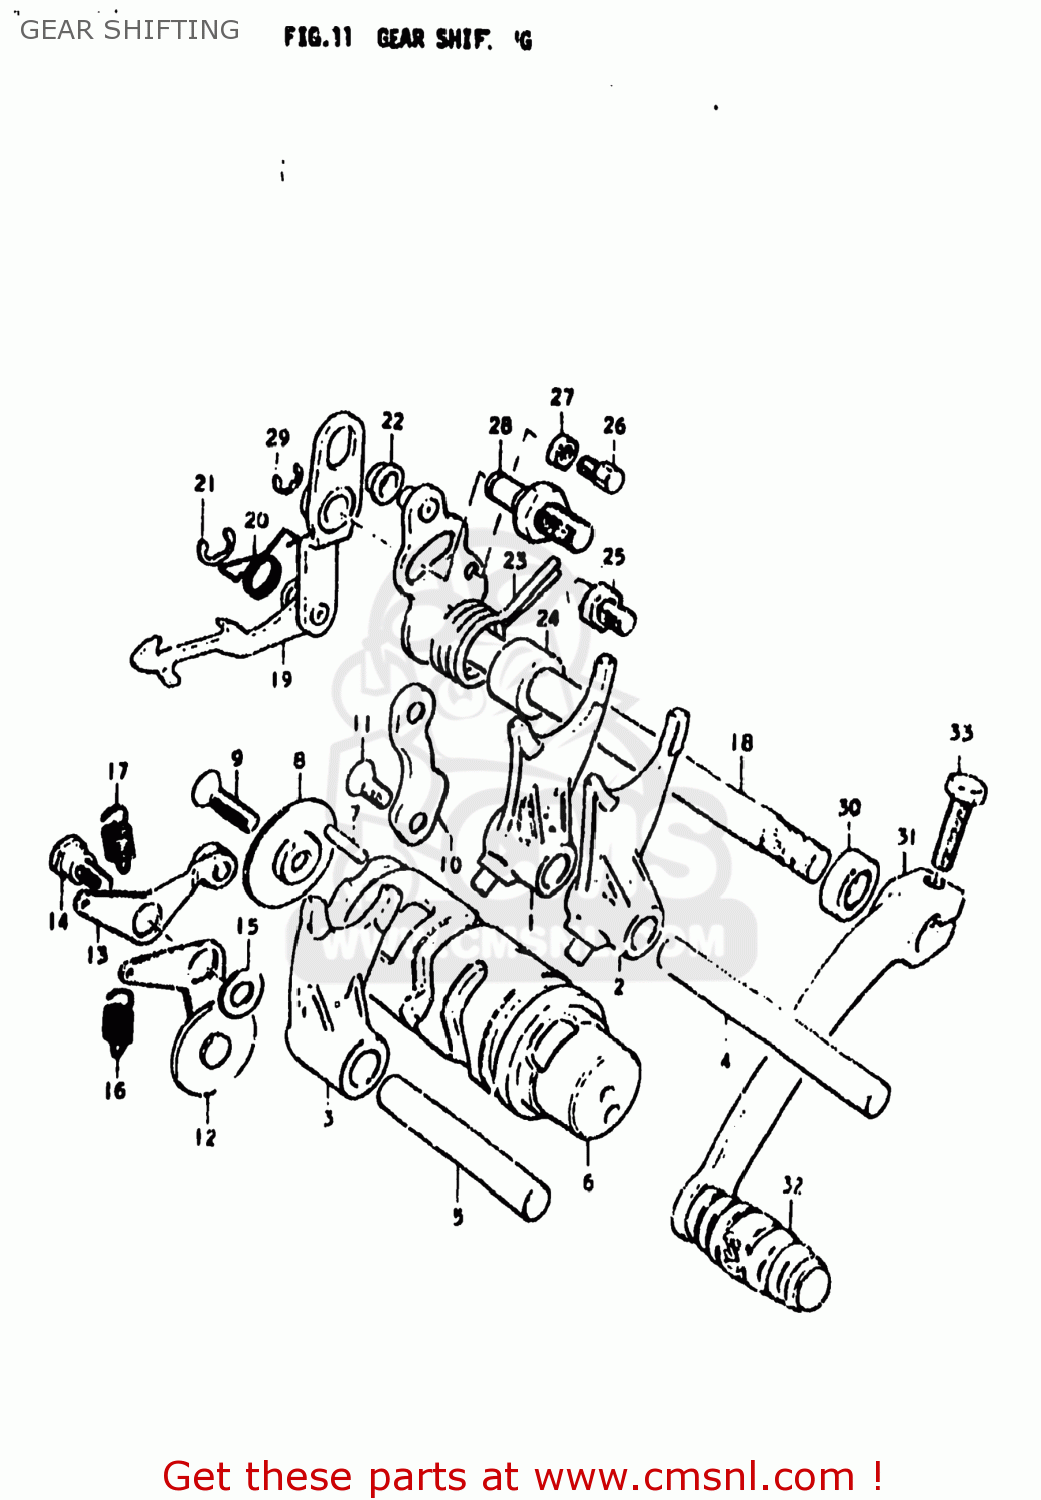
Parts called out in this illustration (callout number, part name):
1	FORK,GEAR SHIFT NO.1
2	FORK,GEAR SHIFT NO.2
3	FORK,GEAR SHIFT NO.3
4	SHAFT,GEAR SHIFT FORK
5	SHAFT,GEAR SHIFT FORK
6	CAM,GEAR SHIFT
7	PIN(4X15.8)
8	HOLDER,GEAR SHIFTING C
9	SCREW
10	GUIDE,GEAR SHIFT CAM
11	SCREW
12	STOPPER,GEAR SHIFT CAM
13	STOPPER,GEAR SHIFT CAM NEUTRAL
14	BOLT(6X18.3)
15	WASHER
16	SPRING
17	SPRING
18	SHAFT,GEAR SHIFT
19	PAWL,GEAR SHIFTING
20	SPRING
21	E RING
22	SPACER(7X10X5)
23	SPRING
24	SPACER(12X20X15.3)
25	STOPPER,GEAR SHIFT CAM
26	BOLT,GEAR SHAFT RETURN SPR SET
27	NUT 6MM
28	STOPPER,GEAR SHIFT CAM
29	E RING 6MM
30	OIL SEAL
31	LEVER ASSEMBLY,GEAR SHIFTING
32	RUBBER,GEAR SHIFT PEDAL
33	BOLT
